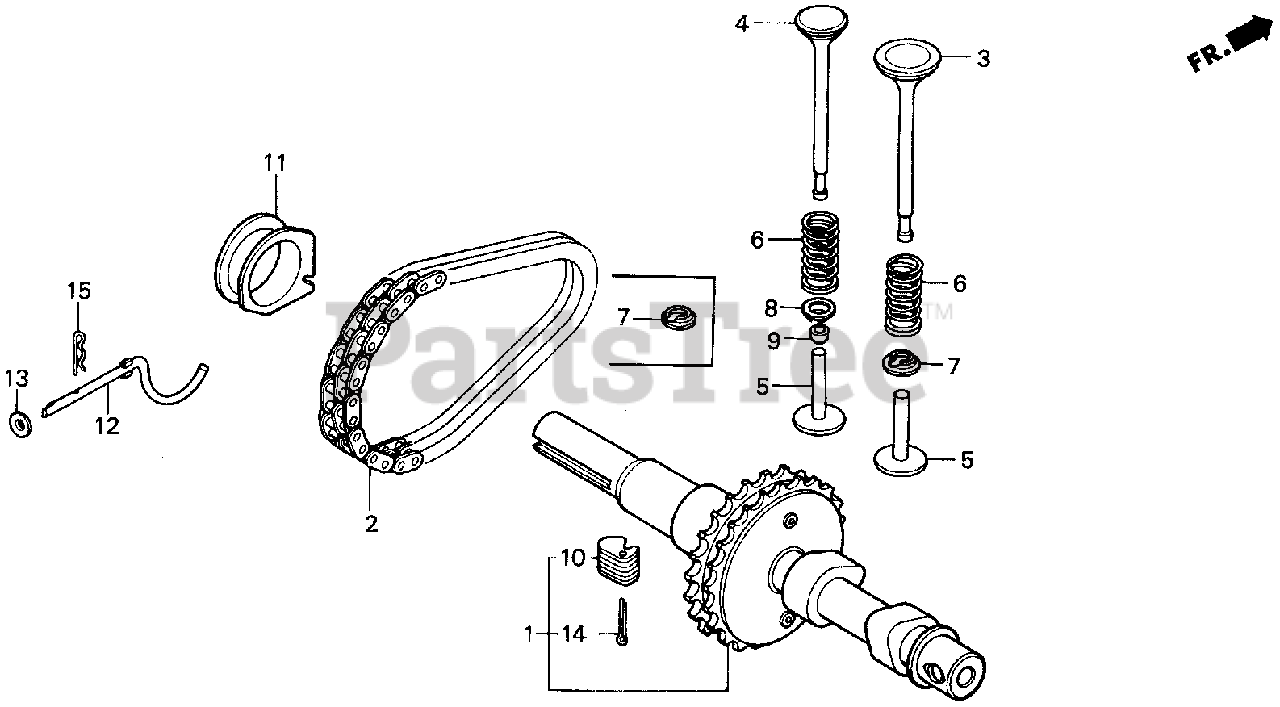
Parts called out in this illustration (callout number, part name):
1	CAMSHAFT ASSY.
2	CHAIN, CAM
3	VALVE, IN.
4	VALVE, EX.
5	LIFTER, VALVE (45.89MM)
5	LIFTER, VALVE (46.04MM)
5	LIFTER, VALVE (46.19MM)
5	LIFTER, VALVE (46.34MM)
6	SPRING, VALVE
7	RETAINER, VALVE SPRING
8	RETAINER, VALVE SPRING
9	ROTATOR, EX. VALVE
10	WEIGHT, GOVERNOR
11	SLIDER, GOVERNOR
12	SHAFT, GOVERNOR
13	WASHER, PLAIN (6MM)
14	PIN, COTTER (3.0X45)
15	PIN, LOCK (10MM)
